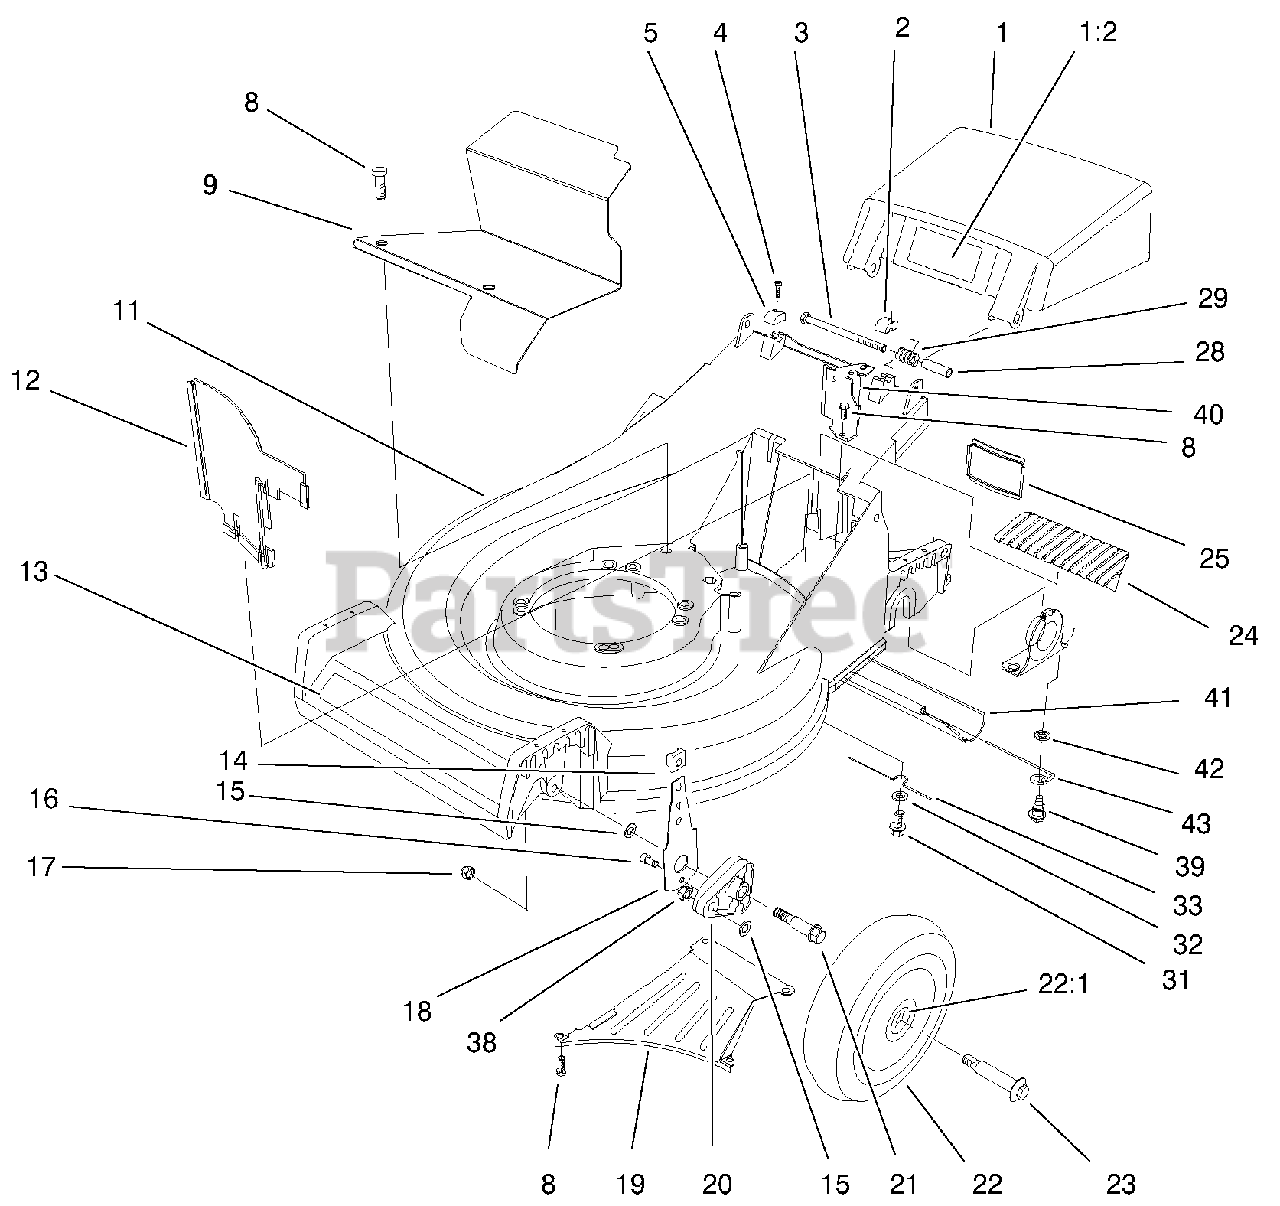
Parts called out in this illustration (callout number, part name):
1	Bag Door
1:2	Decal-Danger
2	Cap-Hinge Bolt LH
3	Screw-HH
4	Screw-Allen Hd
5	Cap-Hinge Bolt RH
9	Panel-Screen
12	Vertical Panel
13	Decal-Deck
14	Knob-Arm
17	Nut-Lock, NI
18	Spring Arm ASM-Front
19	Discharge Ramp
20	Arm-Pivot, Front
21	Screw-Shoulder
22	Wheel ASM
23	Bolt-Shoulder
24	Cover-Top
25	Access Cover
28	Door Spacer
29	Door Spring
32	Washer-Flat
33	Belt Retainer
39	Screw-Shoulder
40	Bracket-Cable Support
41	Trailing Shield
42	Washer-Flat
43	Shield Hanger
